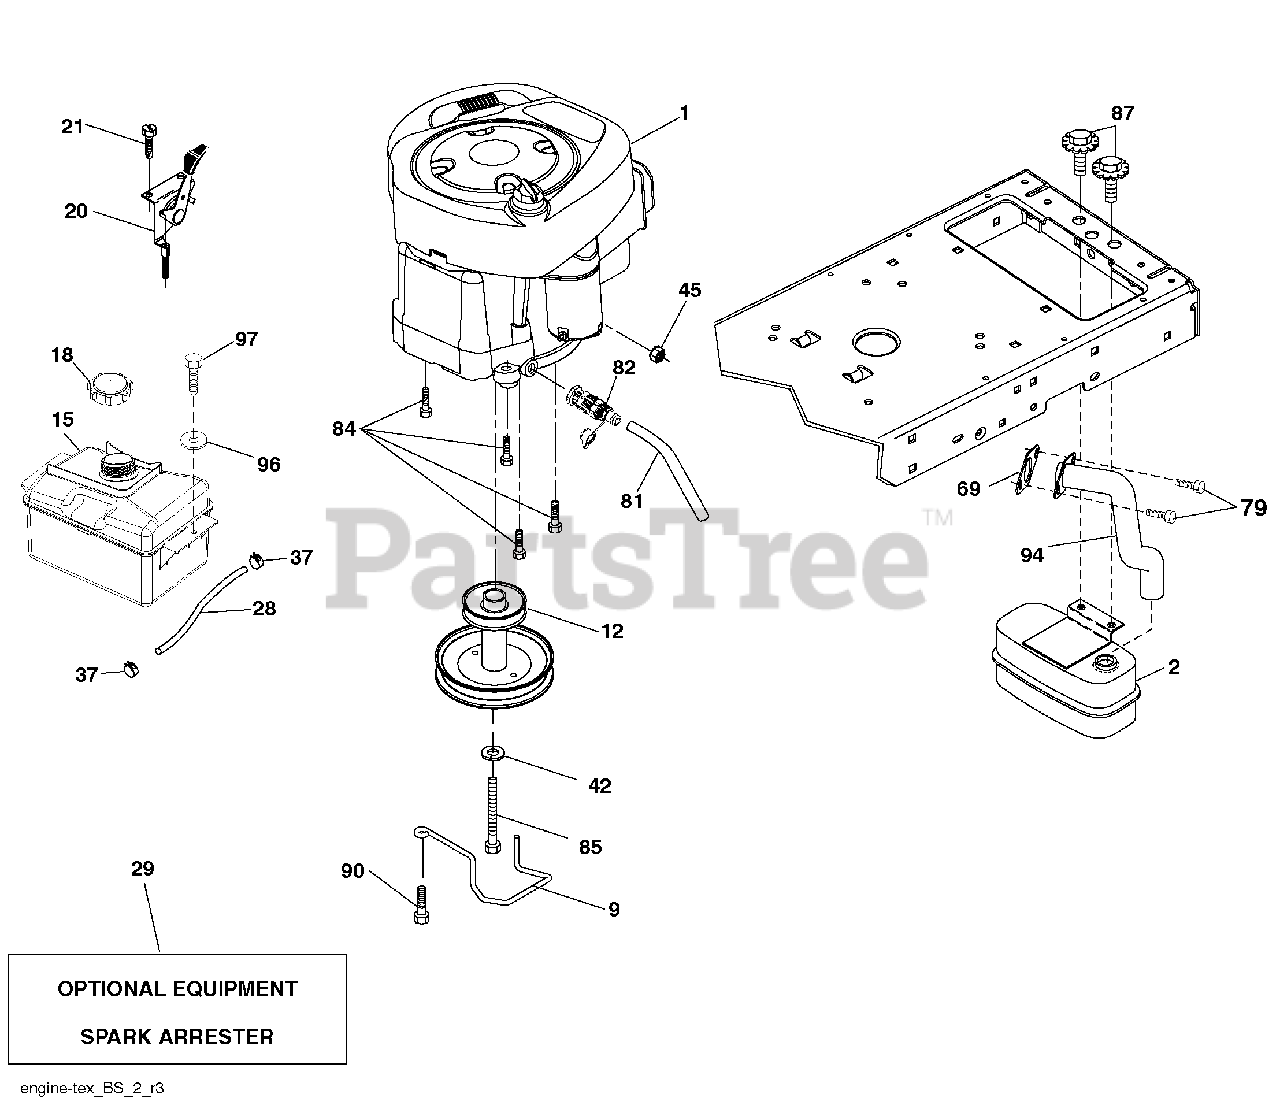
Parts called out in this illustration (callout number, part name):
9	Keeper Belt Engine
12	Pulley Engine
15	Tank Fuel
18	Cap Asm
20	Control Throttle
21	Screw #10 x 0.750 BOS Thread
28	Fuel Line
29	Spark Arrester Kit
37	Clamp Hose
42	Washer Lock 7/16
45	Nut Keps Hex 1/4-20 unc
69	Gasket
79	Screw 5/16-18 x 3/4
81	Tube Drain Oil Easy
82	Valve Drain Oil
84	Screw 3/8-16 x 1/4
85	Bolt Hex 7/16-20 x 4 Gr. 5
87	Bolt 5/16-18 unc x 3/4 w/sems
90	Screw 3/8-16 x 1
94	Exhaust Tube
96	Washer 9/32 x 7/8 x 16 Ga.
97	Screw 1/4-20 x 3/4
